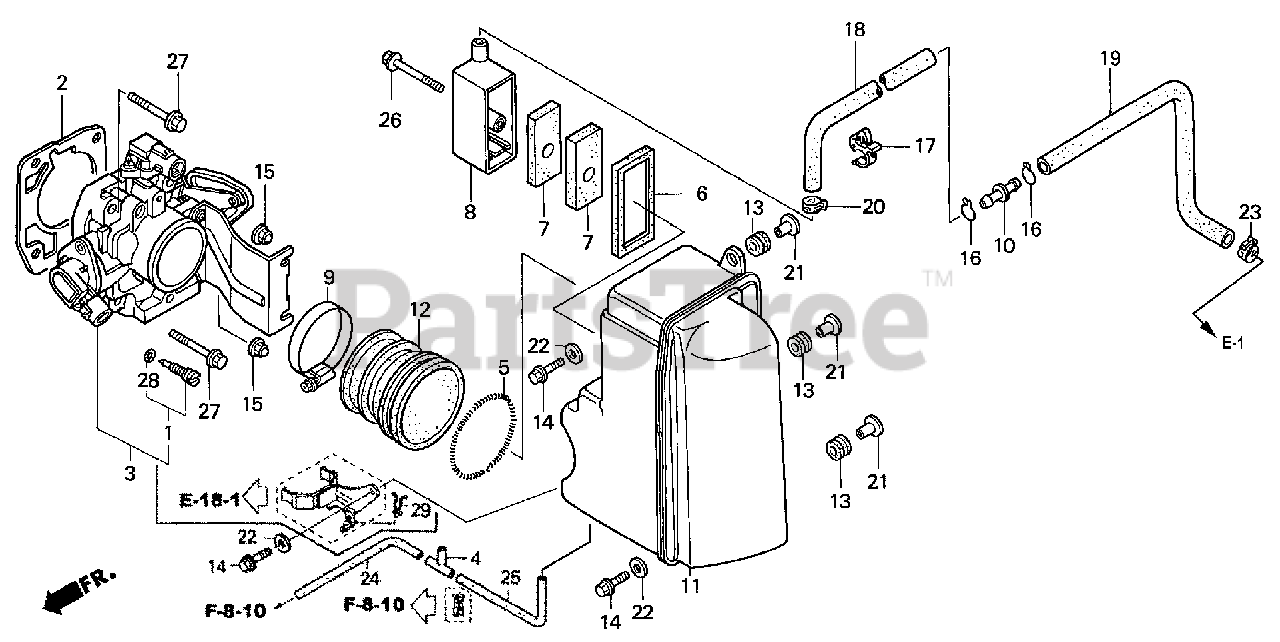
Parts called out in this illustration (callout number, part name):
2	GASKET, THROTTLE BODY (NIPPON LEAKLESS)
3	BODY ASSY., THROTTLE
4	JOINT A, VACUUM TUBE
5	SPRING, AIR FLOW TUBE
6	GASKET, BREATHER
7	ELEMENT, BREATHER
8	COVER, BREATHER ELEMENT
9	CLAMP, AIR FLOW (70)
10	JOINT, BREATHER TUBE
11	CASE, MUFFLER
12	GROMMET, MUFFLER
13	GROMMET, CASE (LOWER)
14	BOLT, FLANGE (6X25)
15	NUT, CAP (8MM)
16	CLIP, TUBE (B12.5)
17	CLIP, CABLE
18	TUBE A, BREATHER
19	TUBE B, BREATHER
20	CLAMP, TUBE (D15)
21	COLLAR, MODULE IGNITION CONTROL CASE (CDI)
22	WASHER, PLAIN (6MM)
23	CLAMP, TUBE (D13)
24	BULK HOSE, VINYL (3.5X6.5X8000) (3.5X6.5X150)
25	BULK HOSE, VINYL (3.5X6.5X8000) (3.5X6.5X190)
26	BOLT, FLANGE (6X50)
27	BOLT, FLANGE (8X40)
28	O-RING (9.8X1.9)
